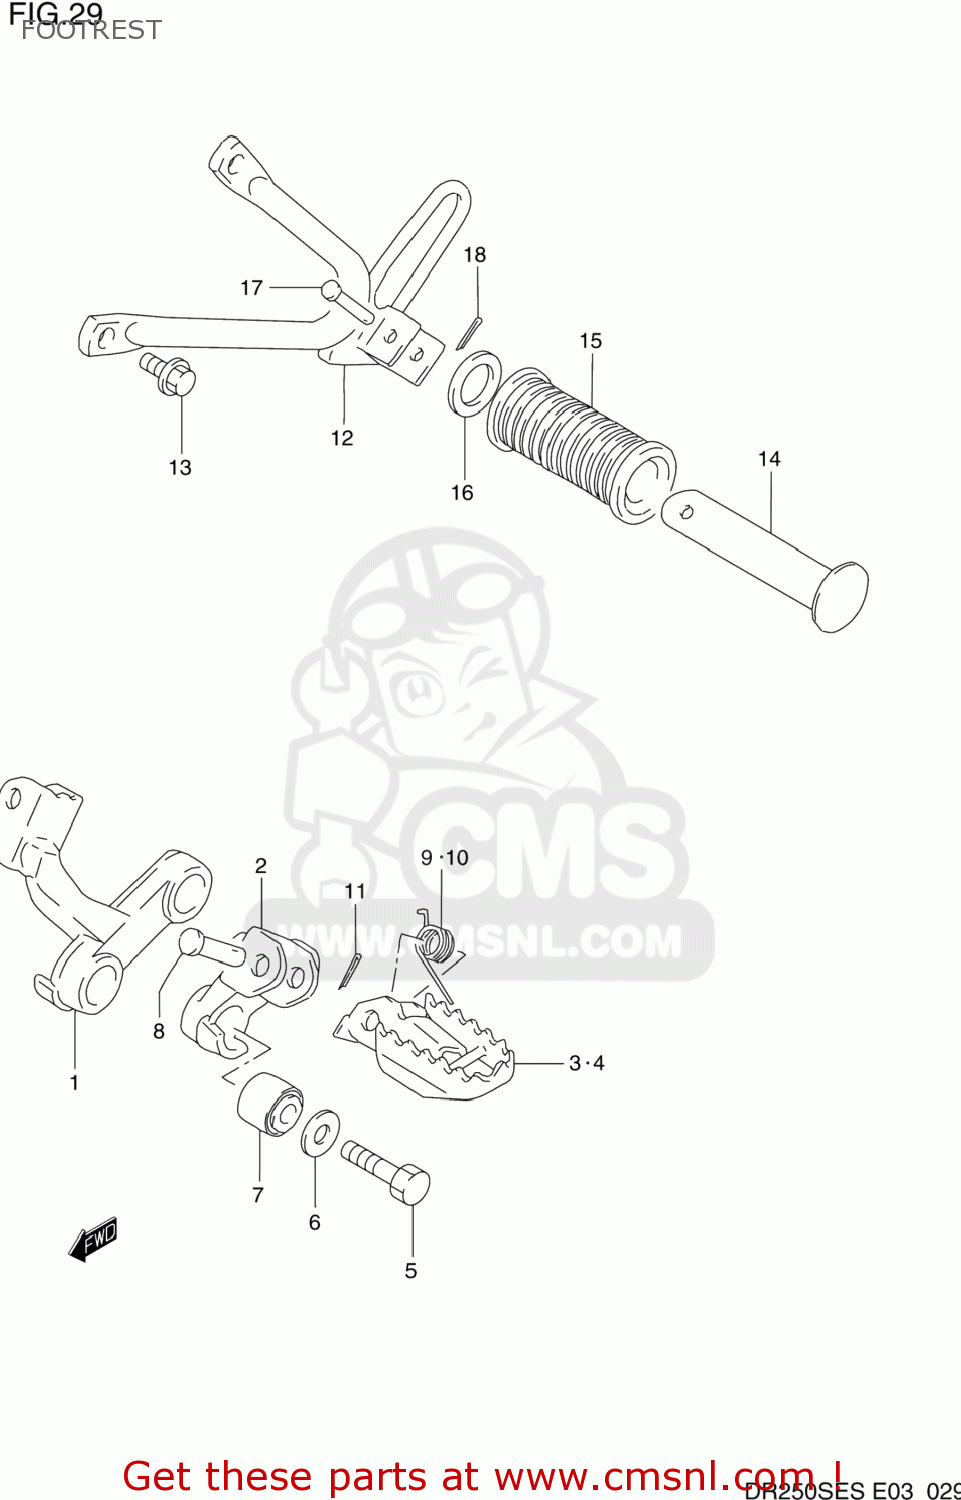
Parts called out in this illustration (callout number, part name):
1	BRACKET,FR FOOTREST,R
2	BRACKET,FR FOOTREST,L
3	FOOTREST COMP,FRONT,RIGHT
4	FOOTREST COMP,FRONT,LEFT
5	BOLT(10X45)
6	WASHER
7	BUSH(10.2X25X19)
8	PIN
9	SPRING
10	SPRING
11	PIN 20X20
12	BRACKET,PILLION FOOT,R(BLACK)
13	BOLT
14	BAR,FOOTREST RUBBER
15	RUBBER,PILLION FOOTREST
16	WASHER (19.5X32X2)
17	PIN
18	PIN
